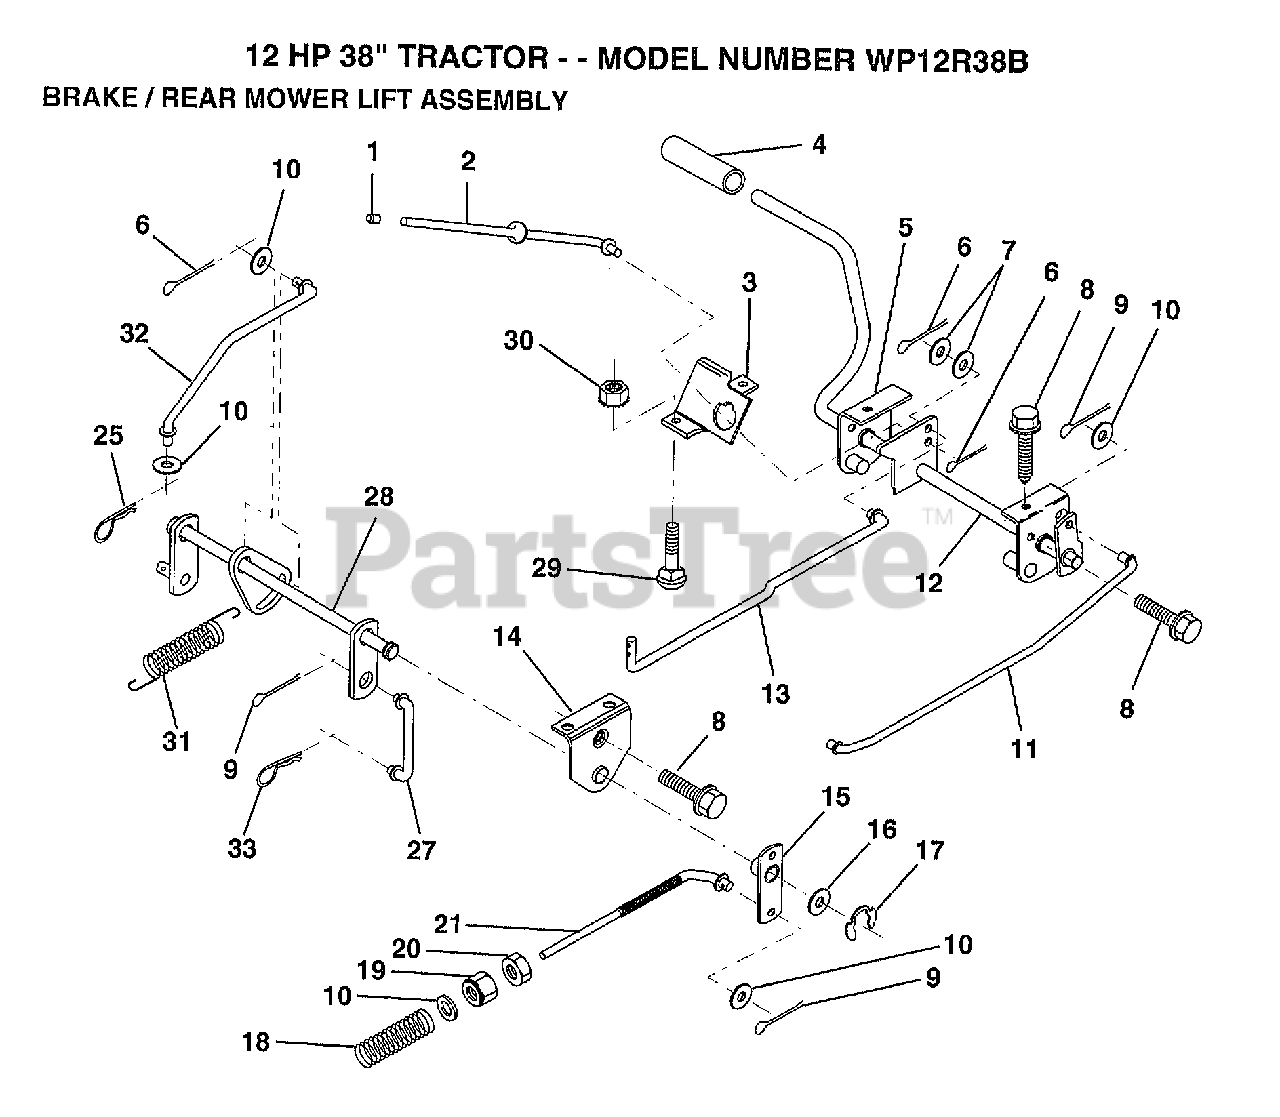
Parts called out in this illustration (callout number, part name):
1	PLUNGER CAP T
2	"ROD,PARK BRAKE"
3	"BRKT,PARK BRAKE"
4	PEDAL COVER T
5	BRK ASM CLUT LH
7	WASHER
8	SCREW LT
9	COTTER PIN
10	WASHER
11	"ROD,FRT BRAKE"
12	ASM CLUTCH/BRK PD
13	"ROD,CLUTCH"
14	"BRKT,LIFT SHAFT"
15	BRAKE PIVOT ARM
16	WASHER T
17	KLIP RING
18	SPRING ROD LT
19	NUT
25	SPRING.RETAINER
27	LINK LIFT REAR LR
28	LIFT ASM MWR RE
31	COUNTER SPRING
32	LINK LIFT LEVER
